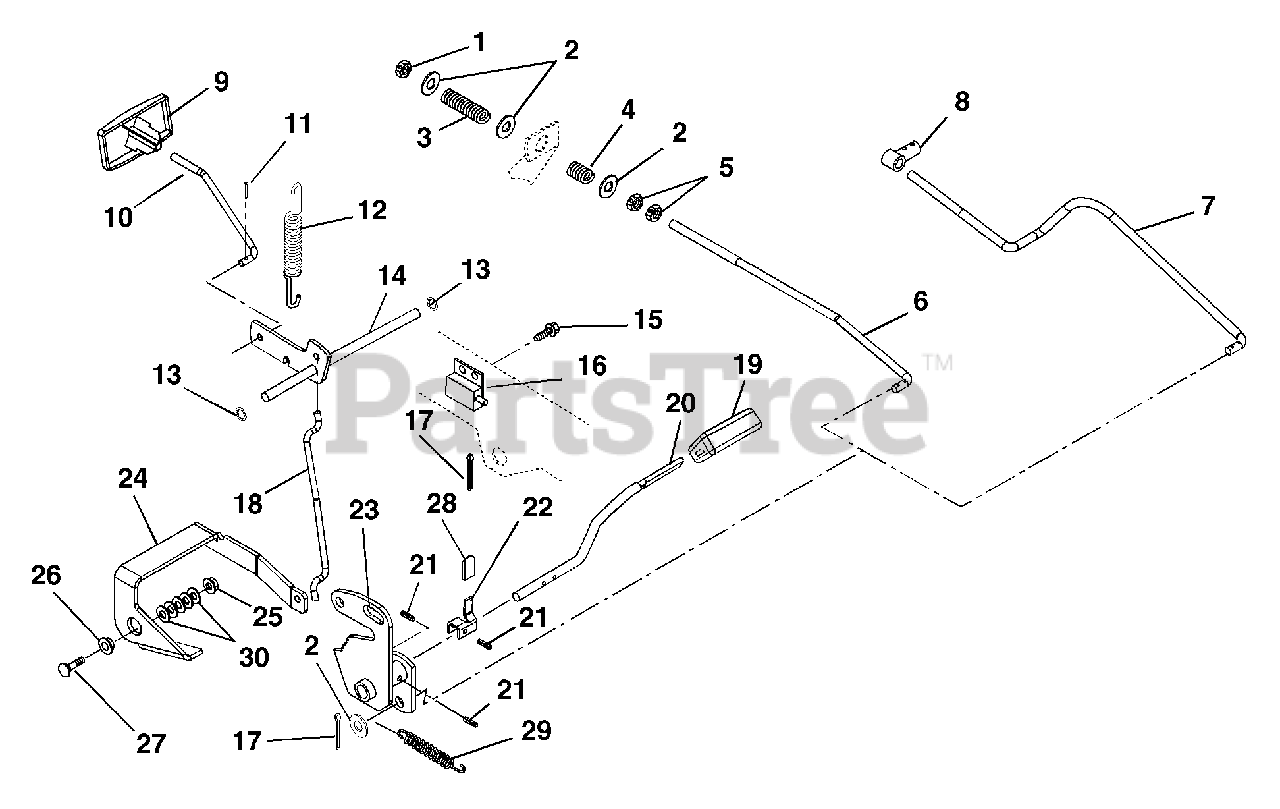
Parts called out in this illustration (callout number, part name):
1	@NUT-LK-CTR-JAM .375-16 YWZC
2	@WSHR-FL-STL.406X.812X.065 YWZ
3	SG-COMP .048X.59X2.06 WLD9
4	SG-COMP .125X.78X1.00 YWZ
5	NUT-HEX-JAM .375-16 YWZC
6	ROD, BRAKE
7	ROD, BRAKE
8	TRUNNION
9	KNOB, PARK BRAKE
10	ROD, PARKING BRAKE
11	PIN-COTR .06X.50
12	SG-TENS .051X.60X2.25 WLD 7.0
13	RG-RTNG-EXT .250X.010
14	BELLCRANK-PARKING BRAKE
15	@SCR-TAP 12-24X.50 HWH TR YWZC
16	SWITCH,INTERLOCK
17	PIN-HAIR INT .08X.18X1.18 YWZC
18	ROD, PARKING BRAKE
19	COVER - PEDAL - BRAKE
20	PEDAL - BRAKE
21	PIN-GRV .188X1.25 TP A
22	LEVER - BRAKE SWITCH
23	WELDMENT, BRAKE ARM
24	LEVER, PARKING BRAKE
25	@NUT-LK-CTR .31-18 YWZC
26	BSHG, FLG .325X.499X.26X.88
27	BLT-RDHDSQSHK.31-18X.75 GR2 YW
28	GRIP .062 X .375 X 1.000 RE
29	SG-TENS .105X.85X5.00 WLD 40
30	WSHR-PLASTIC .390X.875X.062
